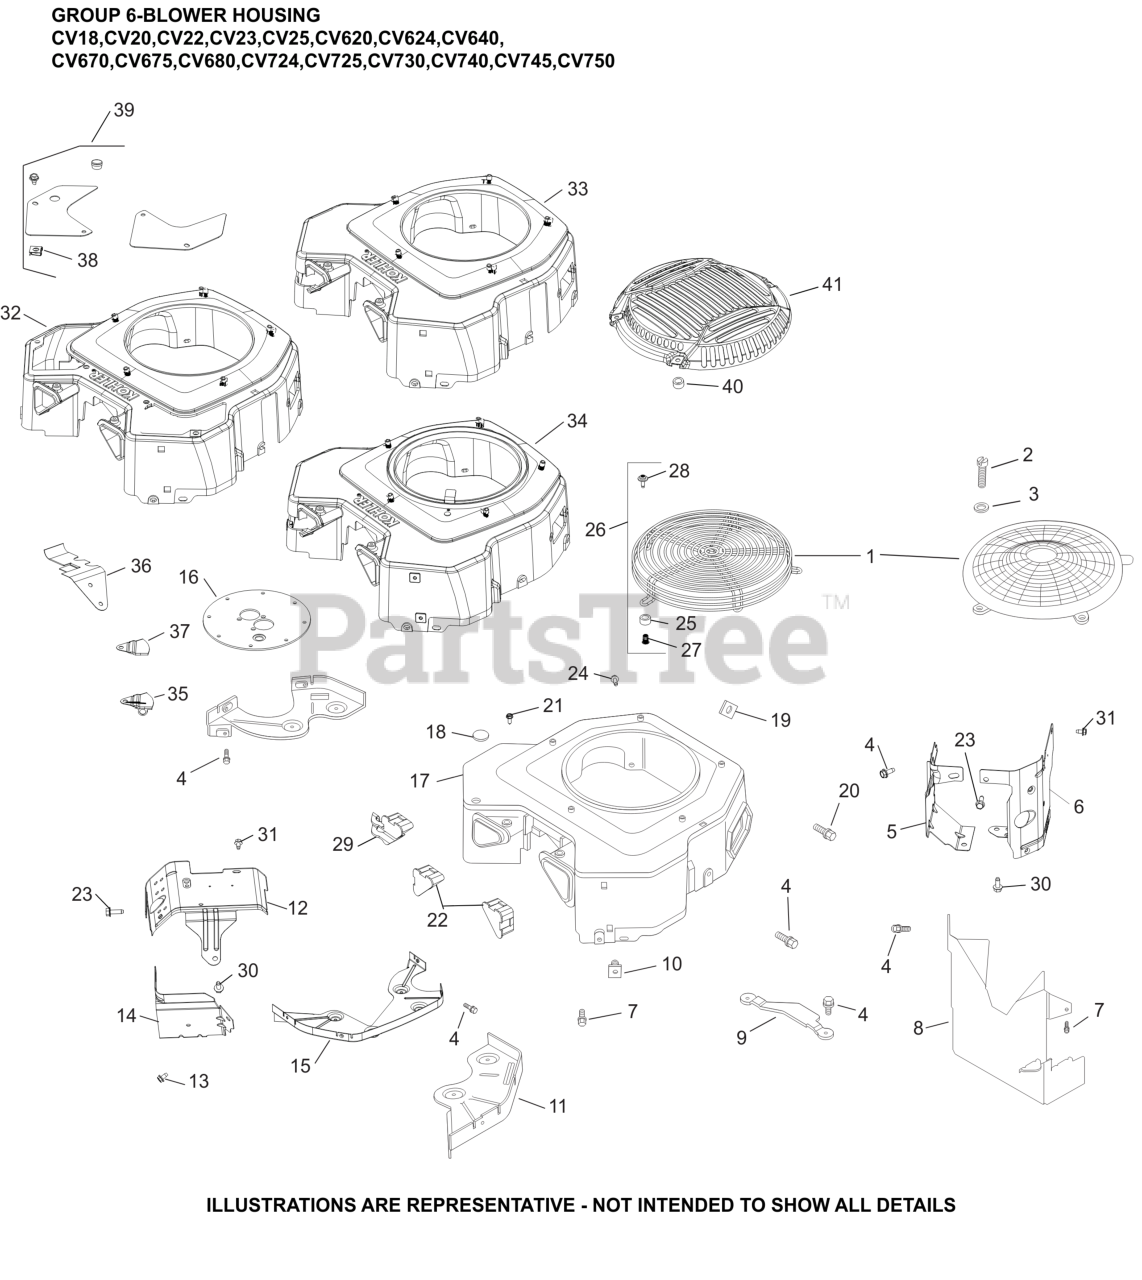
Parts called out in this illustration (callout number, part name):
5	BAFFLE, VALLEY #1 CYLINDER
6	BAFFLE, LEFT BARREL
12	KIT, CYL BAFFEL #1 SIDE
14	BAFFLE, VALLEY #2 CYLINDER
15	KIT, BACKING PLATE
17	KIT, BLOWER HOUSING
20	SCREW, THREAD FORMING
23	SCREW, THREAD FORMING
24	SCREW, THREAD FORMING
27	INSERT, THREADED (M5)
28	SCREW, SEMS
30	SCREW, THREAD FORMING
31	SCREW, THREAD FORMING
41	GUARD, GRASS SCREEN (METAL)
